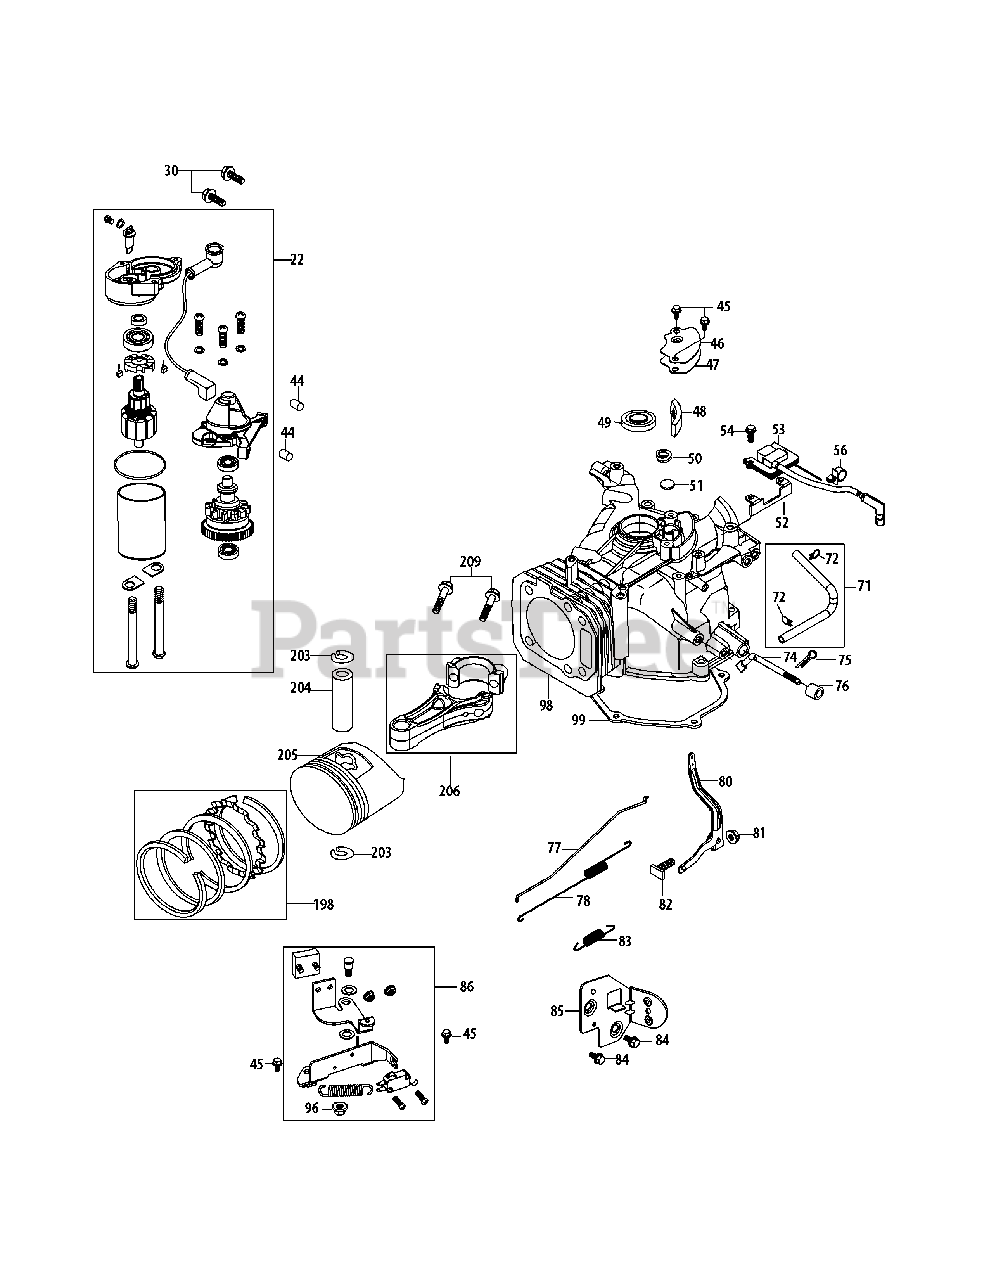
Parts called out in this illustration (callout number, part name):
22	Electrical Starter Assembly
30	Bolt M6×30
44	Dowel Pin 8×8
45	Bolt M6×14
46	Breather Cover Plate
47	Breather Gasket
48	Breather Screen
49	Upper Crankshaft Seal
50	Breather Spring
51	Breather Valve
52	Ignition Coil Bracket
53	Ignition Coil Assembly
54	Bolt M6×18
56	Plastic Clip
71	Breather Hose Assembly
72	Breather Hose Clamp
74	Governor Arm Shaft
75	Governor Arm Cotter Pin
76	Governor Seal
77	Throttle Linkage
78	Throttle Linkage Spring
80	Governor Arm
81	Governor Arm Nut M6
82	Governor Arm Bolt
83	Governor Spring
84	Bolt M6×12
85	Primer Bracket
86	Brake Assembly
96	Brake Arm Nut
98	Short Block Assembly
99	Crankcase Cover Gasket
198	Piston Ring Set
203	Piston Pin Snap Ring
204	Piston Pin
206	Connecting Rod Assembly
209	Connecting Rod Bolt
